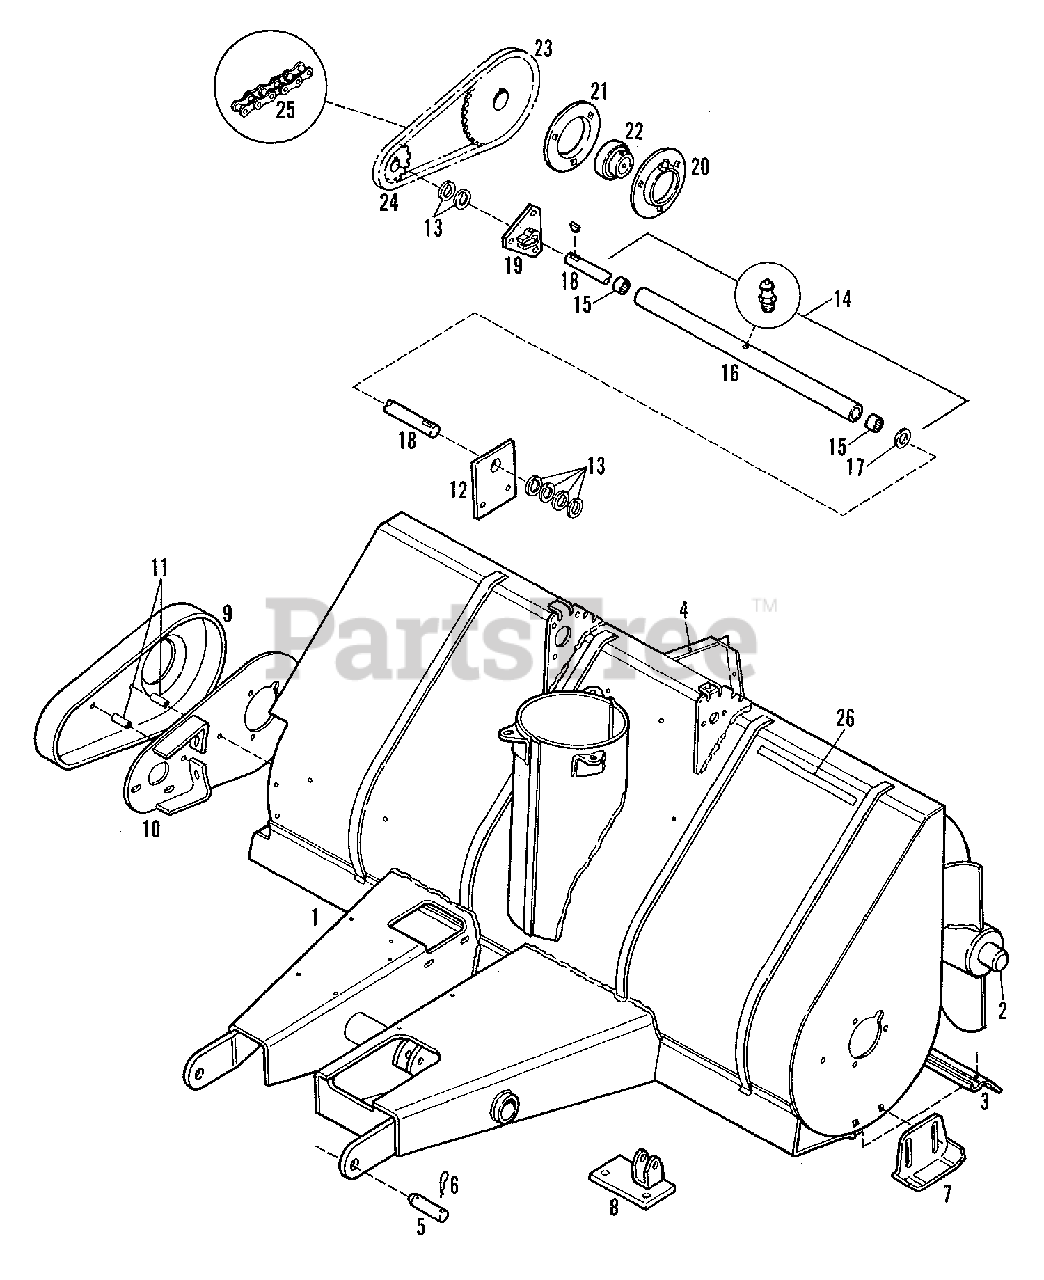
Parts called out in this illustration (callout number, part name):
1	BODY & FRAME ASSEMBLY
2	ROTOR ASSEMBLY
3	BLADE, Scraper
3	CAPSCREW, 5/16NC x 3/4
3	NUT, Jam, 5/16NC
4	DEFLECTOR ASSEMBLY
4	CAPSCREW, 5/16NC x 5/8
4	LOCKWASHER, 5/16
4	NUT, 5/16NC
6	CLIP, Hairpin
7	PLATE ASSEMBLY, Skid
7	CAPSCREW, 3/8NC x 1
7	WASHER, Plain, 7/16 x 1 x 14 Ga.
7	NUT, Whizlock, 3/8NC
8	CYLINDER MOUNT ASSEMBLY
8	CAPSCREW, 7/16NC x 1-1/4
8	LOCKWASHER, 7/16
8	NUT, 7/16NC
9	GUARD, Chain
10	BRACKET ASSEMBLY & SIDE PLATE
10	SCREW, Self-Tapping, 5/16NC x 1/2
10	SCREW, Large Flange, Whizlock, 3/8NC x 2-1/4
10	NUT, Whizlock, 3/8NC
12	PLATE ASSEMBLY, Mounting
12	CAPSCREW, 5/16NC x 1-1/2
12	WASHER, Plain, 7/16 x 1 x 14 Ga.
12	LOCKWASHER, 5/16
12	NUT, 5/16NC
12	CAPSCREW, 3/8NC x 3/4
12	LOCKWASHER, 3/8
14	HOUSING ASSEMBLY
15	BEARING, Roller
16	HOUSING, Bearing
16	FITTING, Lube, 1/4NC
18	SHAFT, Drive
18	KEY, Hi-Pro, 3/16 x 3/4
19	PLATE ASSEMBLY, Mounting
19	CAPSCREW, 3/8NC x 1
19	LOCKWASHER, 3/8
20	FLANGE, Bearing
20	BOLT, Carriage, 3/8NC x 1
20	LOCKWASHER, 3/8
21	FLANGE, Bearing
22	SETSCREW, 5/16NC x 1/2
23	SPROCKET (34T)
23	KEY, Hi-Pro, 5/16 x 1
23	SETSCREW, 5/16NC x 5/8
23	SETSCREW, 5/16NC x 1/2
24	SPROCKET (14T)
24	SETSCREW, 5/16NC x 3/8
25	CHAIN ASSEMBLY
26	DECAL (Safety)
